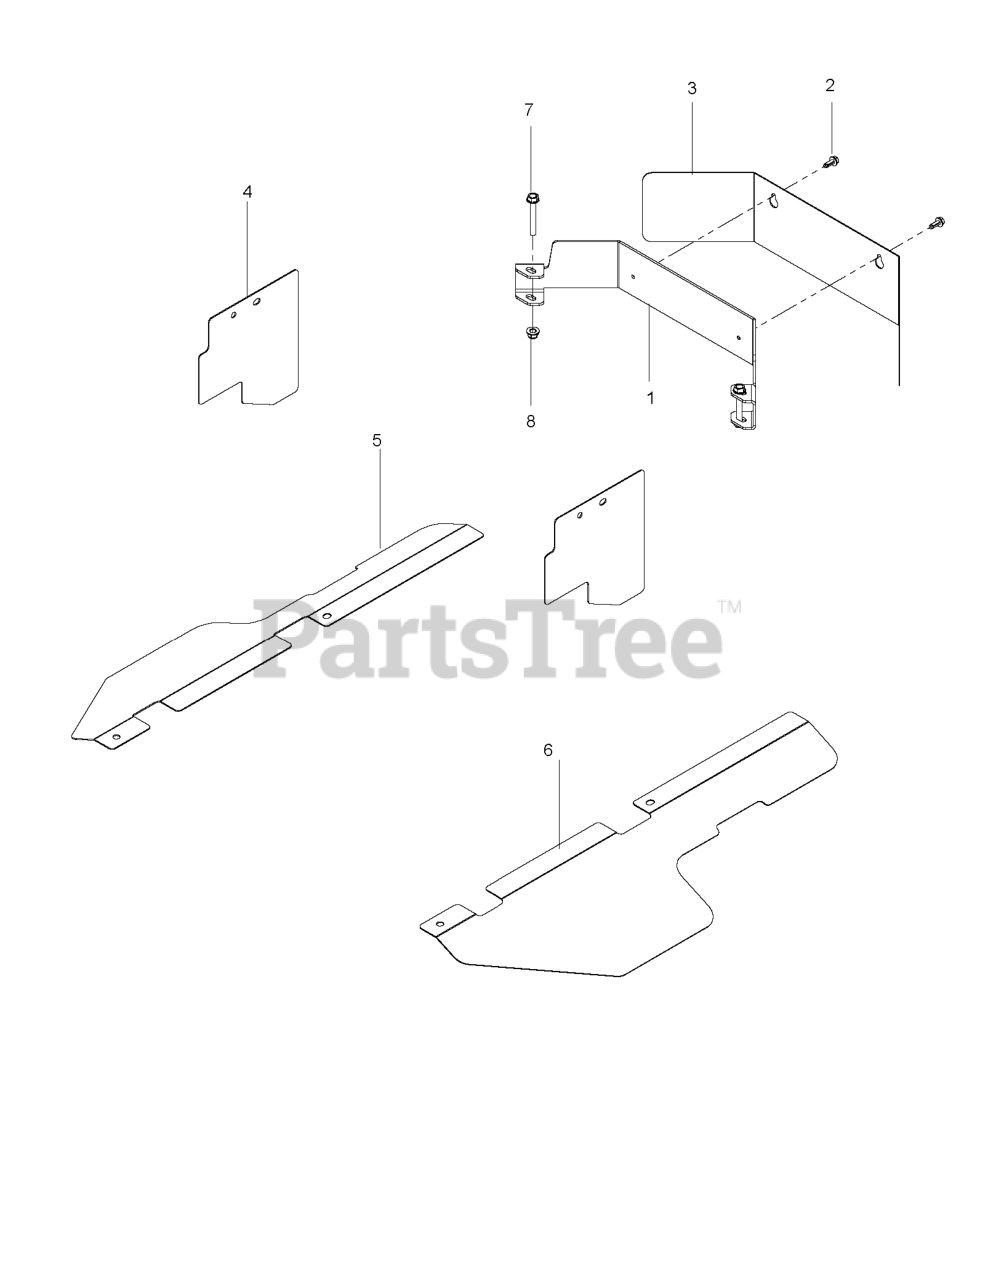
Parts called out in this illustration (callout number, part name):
1	BRACKET.GUARD.EZ.CLUTCH
2	SCREW- 1/4-20 X 5/8
3	GUARD.EZ.CLUTCH.BLK
4	GUARD.MID.EZ.FRAME.BLK
5	GUARD.RH.EZ.COMBI.BLK
6	GUARD.LH.EZ.COMBI.BLK
7	HHFS 5/16-18 X 2.25 GD 5
8	5/16-18 NYLOC FLANGE NUT
